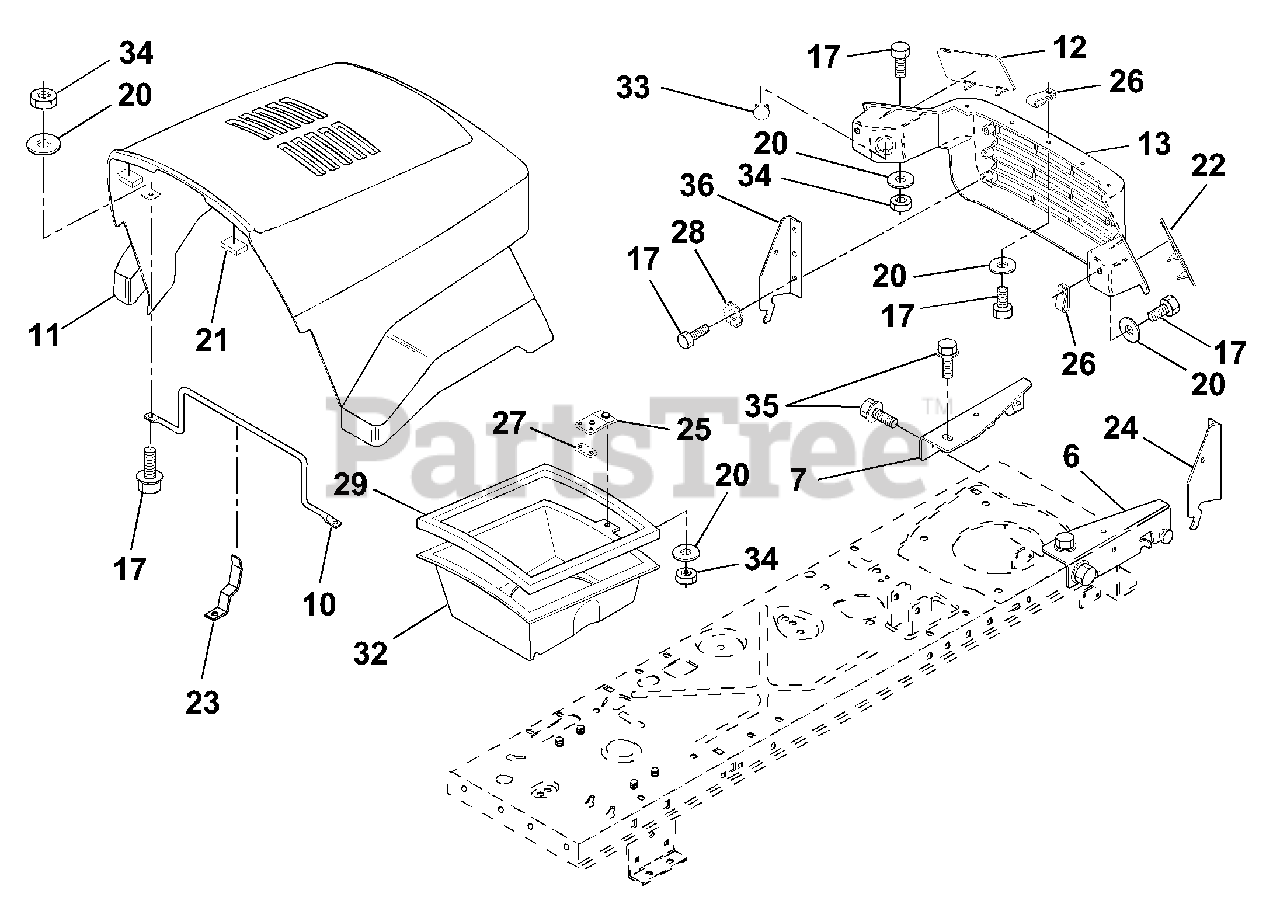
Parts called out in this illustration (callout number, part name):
6	Bracket Asm. Pivot Hood RH
7	Bracket Asm. Pivot Hood LH
10	Brace Hood
13	Grille
17	Bolt Fin Hex 1/4-20 x 5/8
20	Washer, Flat 1/4
21	Bumper Hood
23	Latch Hood
24	Bracket Pivot Hood RH
25	Clip Asm. Duct Air
26	Clip Tinnerman
27	Clip Tinnerman
28	Washer Lock Ext. Tooth
29	Strip Foam
32	Duct Air Hood
33	Plug, Socket, Light
34	Nut Crownlock 1/4-20 Unc
35	Screw Thdrol 5/16-28 x 3/4
36	Bracket Pivot Hood LH
